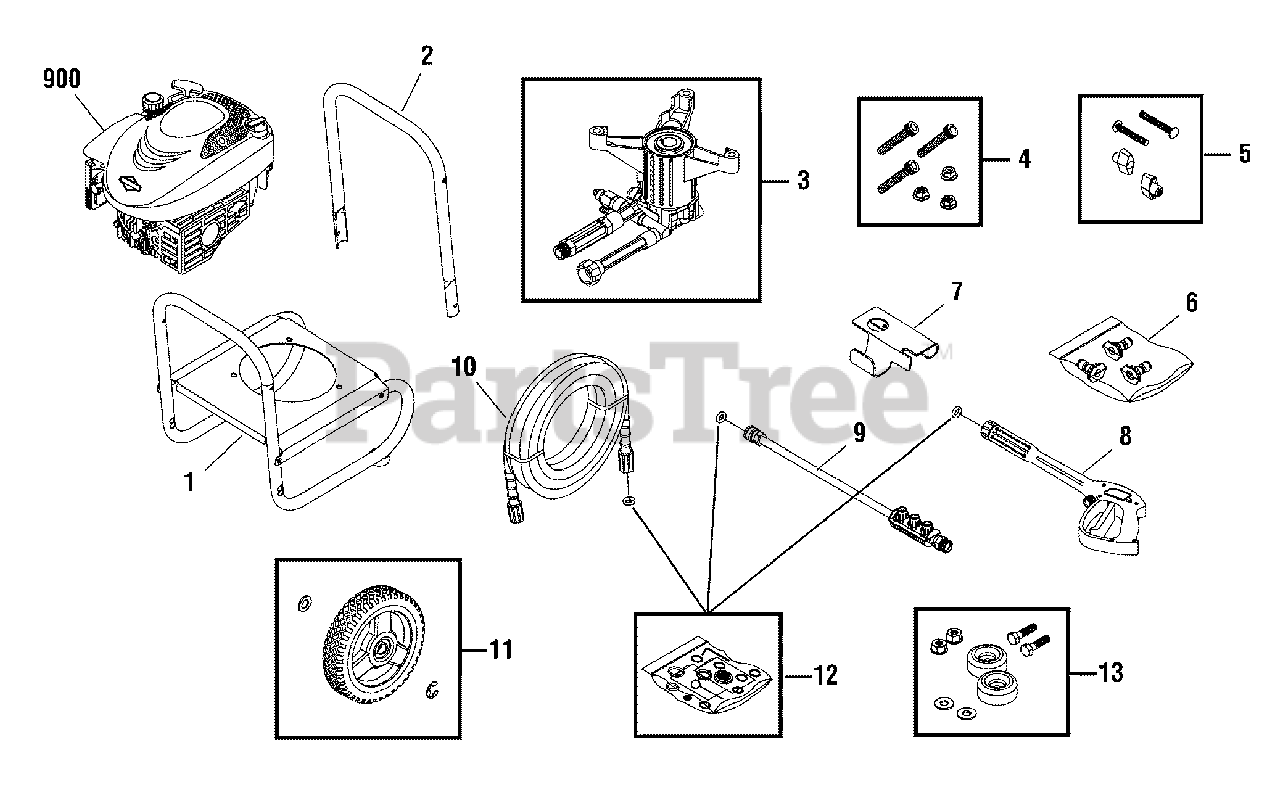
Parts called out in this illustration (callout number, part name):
3	PUMP
4	KIT, Hardware, Pump Mounting
5	KIT, Hardware, Handle
6	KIT, QC Nozzles
8	GUN
10	HOSE
12	KIT, O-Ring
13	KIT, Vibration Mount
900	* ENGINE
